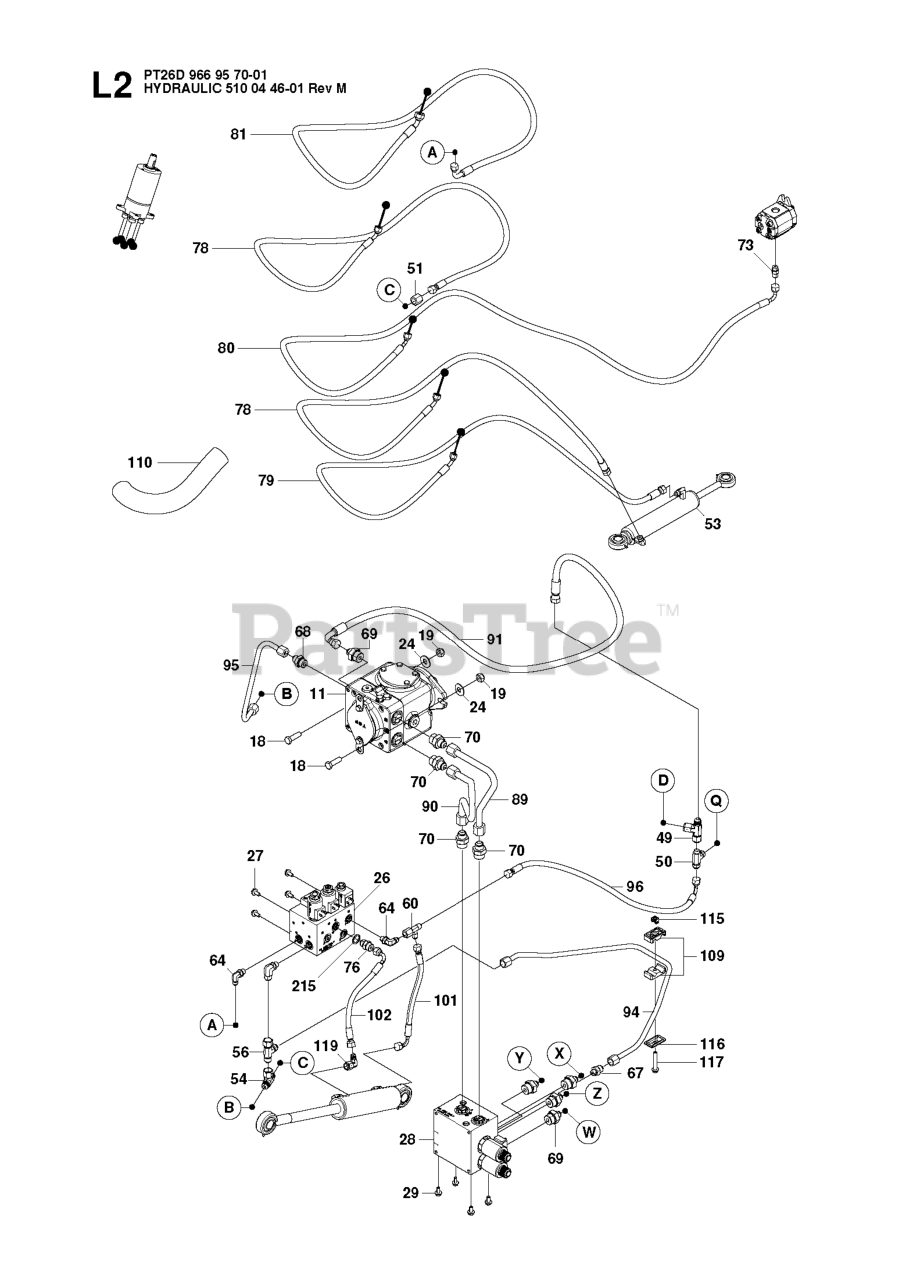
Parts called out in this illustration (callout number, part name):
53	HYDRAULIC CYLINDER
119	PIPE FITTING
215	O-RING 12X2 NITRIL
